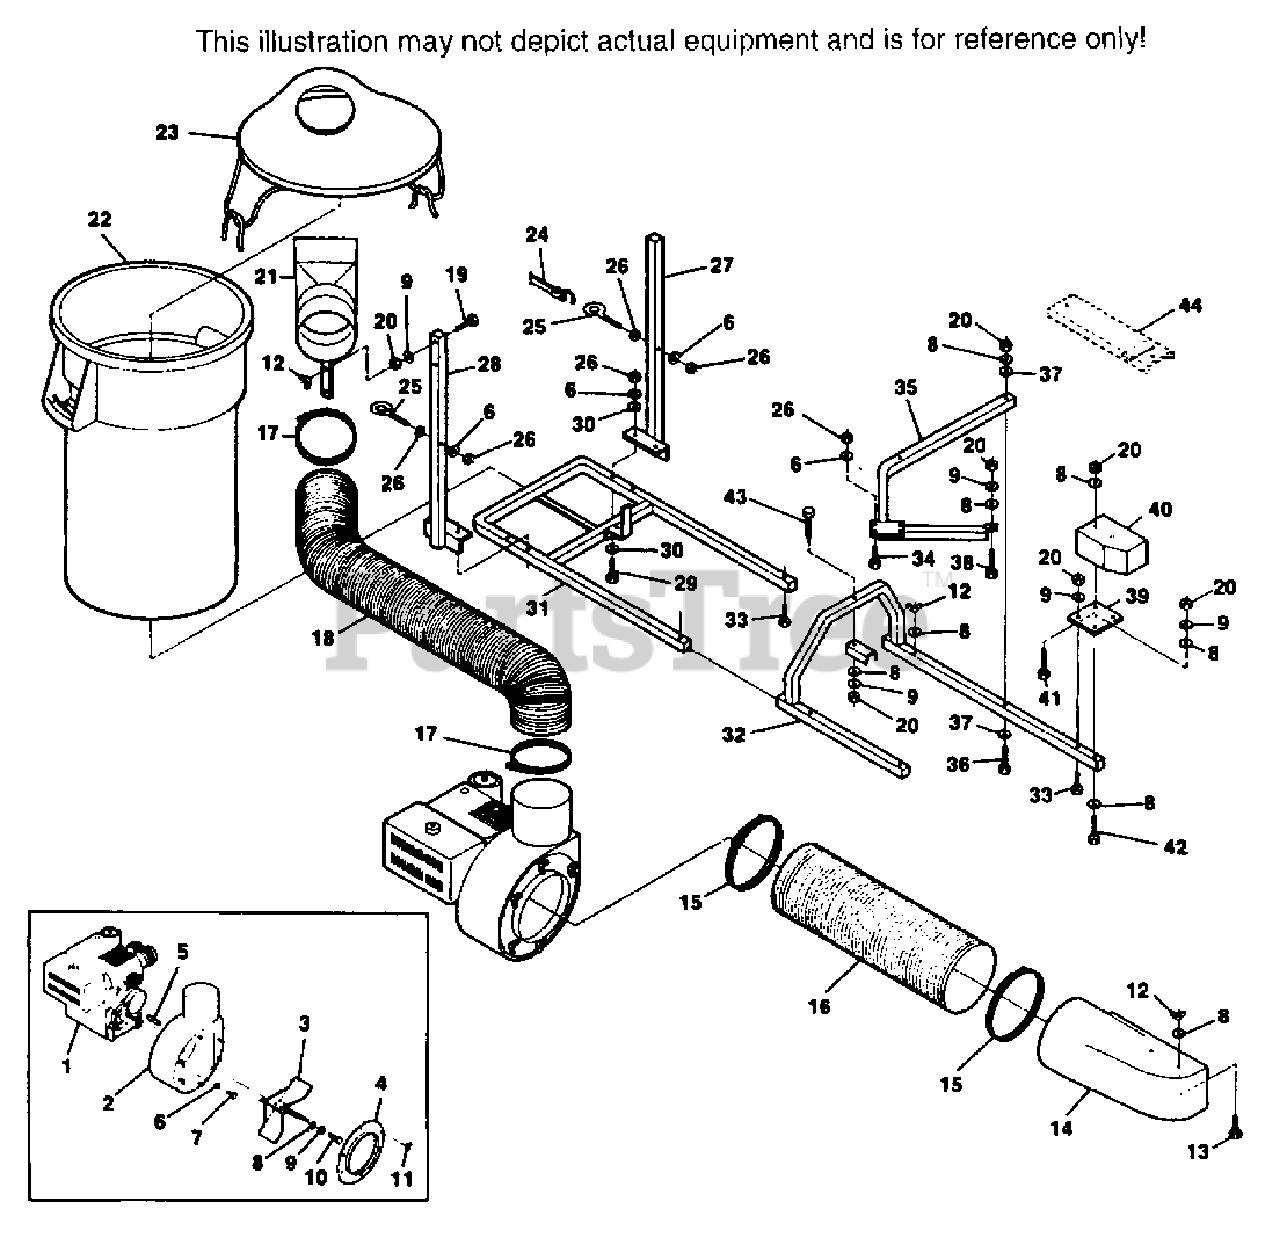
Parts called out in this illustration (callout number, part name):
1	ENGINE, 5 HP I.C.(1" CRANKSHAFT)
2	BLOWER HOUSING ASSEMBLY
3	FAN ASSEMBLY(1" BORE)
3	FAN ASSEMBLY(FOR 3/4" CRANKSHAFT INCLUDES
4	INLET ADAPTOR
5	KEY 1/4 X 1/4 X 1 1/2"(FOR 1" CRANKSHAFT
5	KEY AND BUSHING KIT(USED ON 3/4" CRANKSHAFT)
7	BOLT 5/16-24 X 1"
11	WING NUT 5/16-18
12	WING NUT 3/8-16
14	BOOT
15	CLAMP 8"
16	HOSE 8"
17	CLAMP 6"
18	HOSE 6"
21	HOSE SUPPORT
22	BUCKET
23	BUCKET COVER
24	RUBBER STRAP
25	EYEBOLT 5/16-18 X 2 3/4"
27	BUCKET BRACE LH
28	BUCKET BRACE RH
31	BUCKET SUPPORT FRAME
32	MAIN FRAME
35	ENGINE MOUNTING FRAME
37	WASHER 3/8 X 1 1/2 X 7 GA.
39	BALLAST SUPPORT
40	BALLAST
44	FRAME EXTENSION
